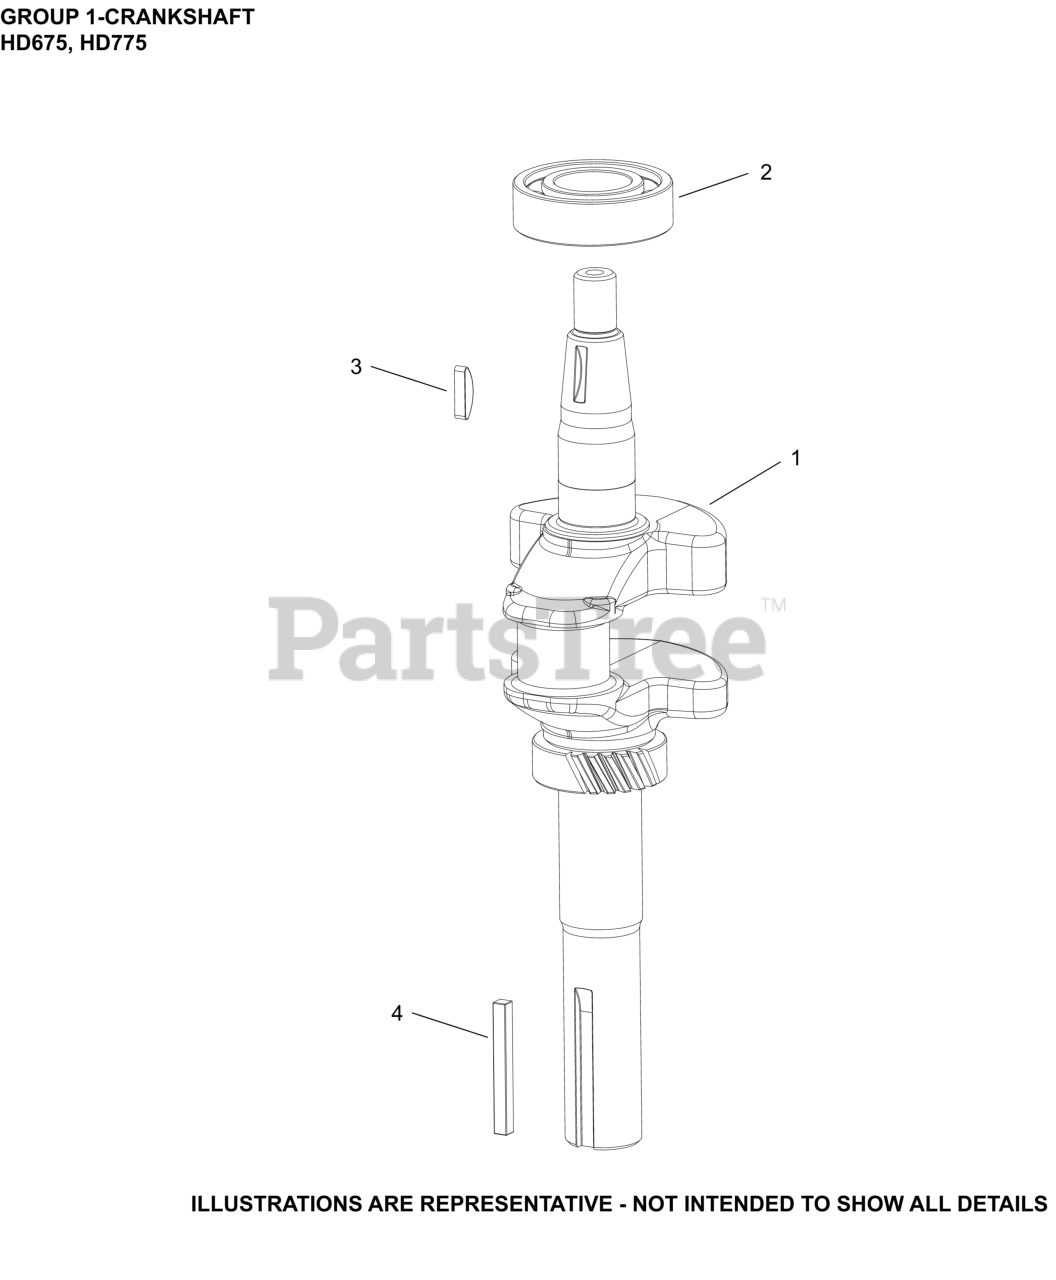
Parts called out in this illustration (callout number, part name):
1	CRANKSHAFT ASSEMBLY
2	BEARING, BALL
3	KEY, FLYWHEEL
